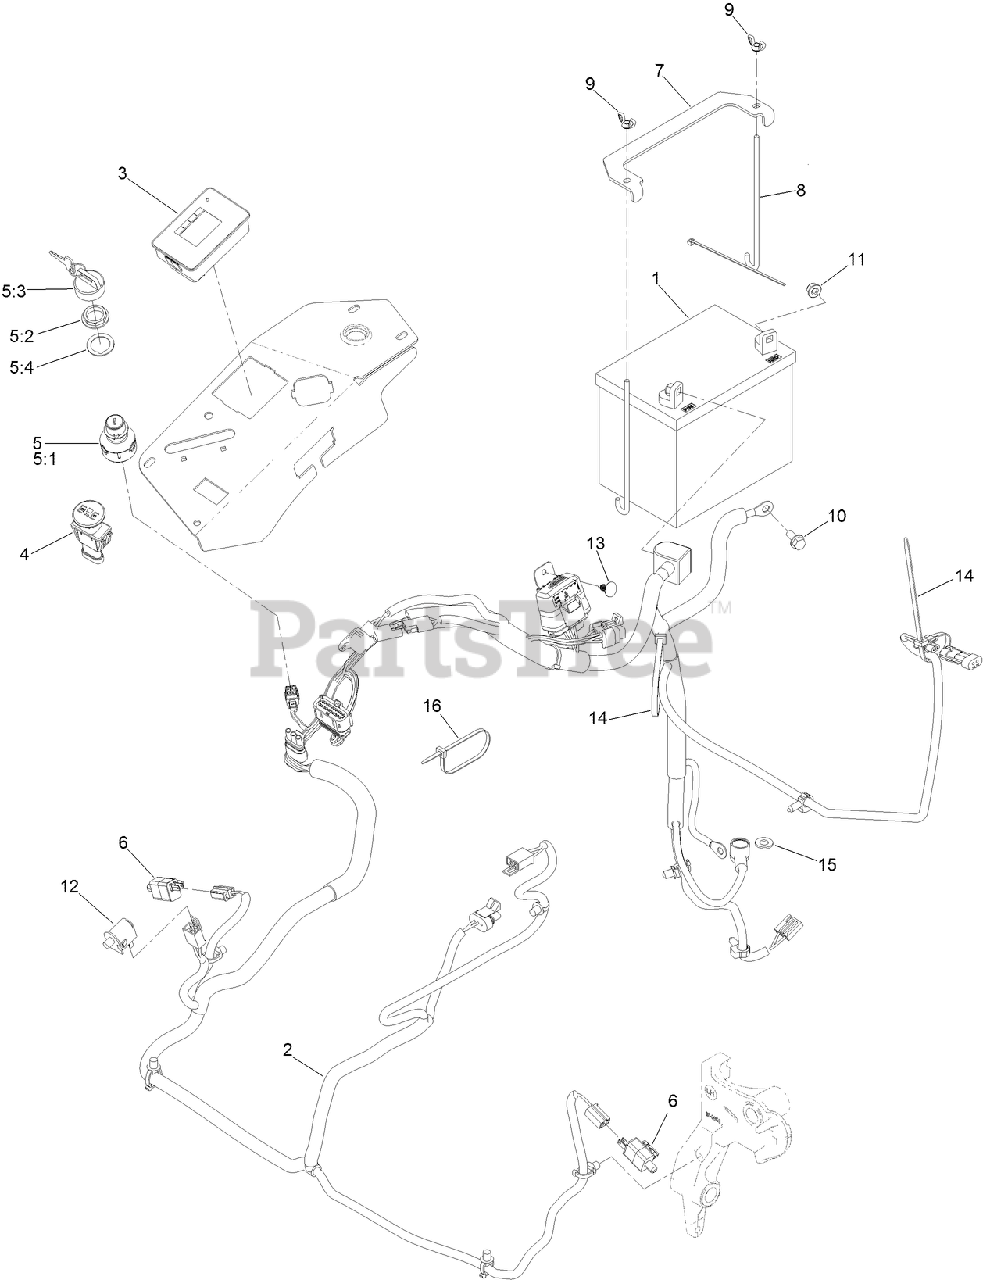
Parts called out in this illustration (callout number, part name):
1	BATTERY-DRY
2	WIRE HARNESS ASM
3	METER-HOUR
4	SWITCH-PTO, SEALED
5	IGNITION SWITCH ASM
5:1	Deck ASM
5:2	NUT-MOUNTING
5:3	IGNITION KEY SET
5:4	WASHER-BACKUP
6	SWITCH
7	STRAP-TIE DOWN, BATTERY
8	BOLT-HOLDDOWN
9	WINGNUT
10	SCREW-HH
11	NUT-HF, NI
12	SWITCH-BAIL
13	PLUG-PLASTIC
14	TIE-PLASTIC
15	WASHER-FLAT
16	TIE-CABLE
